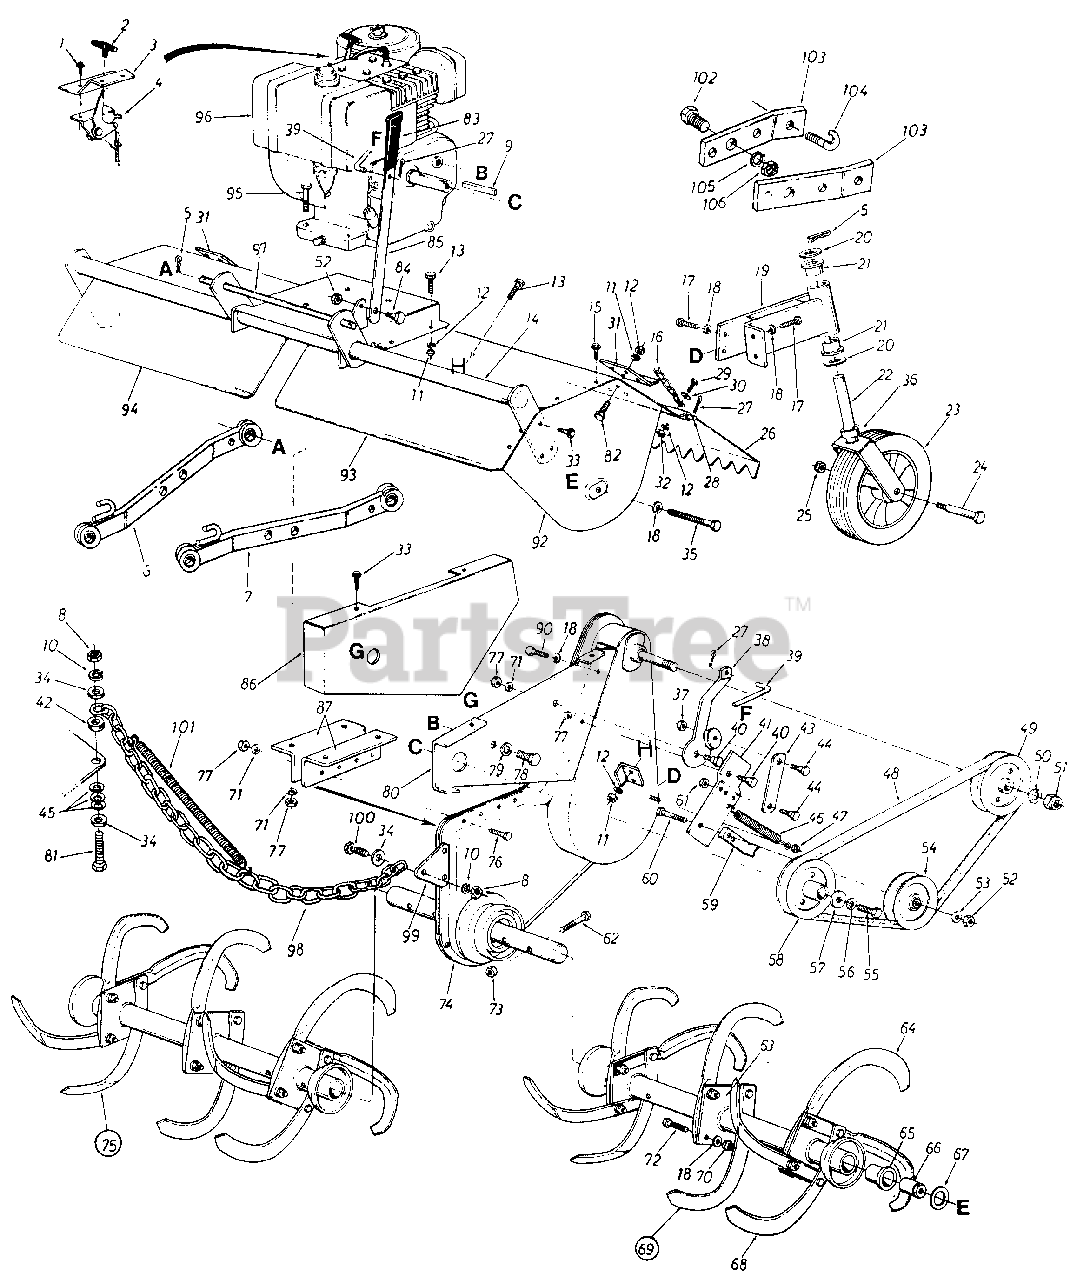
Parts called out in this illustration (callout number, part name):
1	Hex Wash. Hd. Self-Tap Scr. #8 x .50" Lg .
2	Throttle Control Knob
3	Throttle Control Bracket
4	Throttle Control Ass'y. Comp.
5	Internal Cotter Pin
6	Draft Bar Ass'y. R.H.
7	Draft Bar Ass'y. L.H.
8	Hex Nut 3/8-24 Thd.
9	Sq. Key '/4" x 1/4" x 2.00" Lg.
10	L-Wash. 3/8" I.D.
11	Hex Nut 1/4-28 Thd.
12	L-Wash. 1/4" I.D.
13	Hex Bolt '/4-28 x .62" Lg.
16	#2 Dog Chain x 20" Lg.
17	Hex Wash. Hd. Self-Tap Scr. 3/8-24 x . 75 " Lg .
18	L-Wash. 3/8" I.D.
21	Flange Bearing 3/4" I.D. x 1.00" O.D.
24	Shoulder Bolt .623" I.D. x 3.62" Lg.
25	Hex Cent. L-Nut 7/16-14 Thd.
28	L.H. Flap Rod
29	Hex Bolt 1/4-20 x .62" Lg.
30	Fl-Wash. 1/4" I.D.
33	Hex Wash. Hd. Self-Tap Scr. 1/4" x.62" Lg.
34	Fl-Wash. .385" I.D. x 1.0" O.D. x .135 Thk.
35	Hex Bolt 3/8-16 x 1.25" Lg.
36	Spacer .752" I.D. x 1.25" O.D.
37	Hex Cent. L-Nut 5/16-18 Thd.
40	Shoulder Bolt 7/16" Dia. x 1.75" Lg.
45	Fl-Wash. .406" I.D. x .74" O.D. x .063 Thk.
46	Extension Spring .62" O.D. x 6.12" Lg.
47	Hex Crown Nut 3/8-24 Thd.
48	"V"-Belt 1/2" x 43" Lg. (Kevlar)
49	1/2" "V"-Pulley 4.75" O.D. x .625" Bore
50	L-Wash. 5/8" I.D.
51	Hex Ins. L-Nut 5/8-18 Thd.
52	Hex Cent. L-Nut 3/8-16 Thd.
53	Fl-Wash. 3/8" I.D.
54	Idler Pulley 4.0" O.D.
55	Hex Bolt
56	L-Wash. 7/16" I.D.
57	Fl-Wash. 7/16" I.D. x 1.38" O.D.
58	1/2" "V"-Pulley .475" O.D. x 1.00" Bore
61	Hex Cent. L-Nut 5/16-18 Thd.
62	Hex Bolt 7/16-14 x 2.00" Lg.
66	Spacer
67	Thrust Wash. 1/2" I.D. x 1.55" O.D.
71	L-Wash. 5/16" I.D.
72	Hex Bolt 3/8-24 x 1.5" Lg.
73	Hex Cent. L-Nut 7/16-14 Thd.
77	Hex Nut 5/16-18 Thd.
78	Hex Bolt 1/2-20 x .88" Lg. (Grade 5)
79	L-Wash. 1/2" I.D.
80	Clutch Support Bracket
81	Hex Bolt 3/8-24 x 1.75" Lg.
82	Hex Bolt 1/4-28 x .75" Lg.
83	Plastic Grip
84	Shoulder Bolt .498 Dia. x .212 Lg.
85	Clutch Handle
96	8 H.P. Engine
97	Tiller Mounting Shaft 16"
98	Chain 23" Lg.
99	Tiller Mounting Bracket
100	Hex Bolt 3/8-24 x 1.25" Lg.
101	Extension Spring
102	Hex Bolt 5/8-18 x 1.62" Special
103	Drag Link Extension
104	Hitch Chain Hook
105	L-Wash. 5/8" I.D.
106	Hex Jam Nut 5/8-18 Thd.
04975-0637	PLATE ASSY-SIDE-LH - POWDER BLACK (0637)
04978-0637	SUPPORT-SWIVEL WHE - POWDER BLACK (0637)
04983-0637	L.H.-Tine Shield - POWDER BLACK (0637)
14298-0637	SHROUD-CLUTCH SUP - POWDER BLACK (0637)
